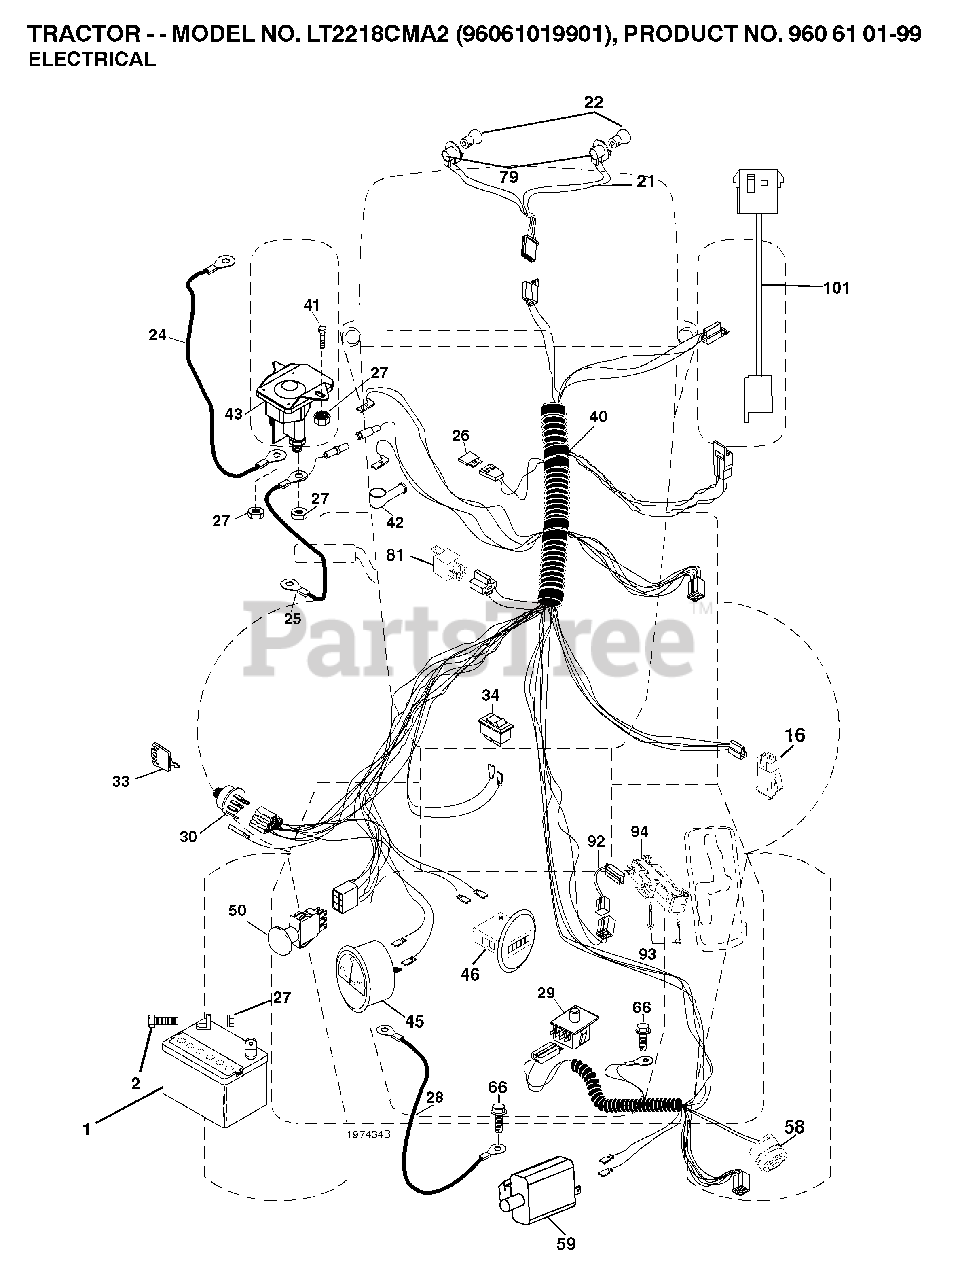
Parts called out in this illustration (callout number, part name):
1	BATTERY 12V .35 AMP
16	SWITCH INTERLOOK PUSH-IN
21	HARNESS.W/LIGHT SOCKET
22	LIGHTBULB
24	BATTERY CABLE GT
25	CABLE BATTERY
26	FUSE 20AMP
27	NUT
28	CABLE GROUND
29	SWITCH.SEAT.DP W/RAMPS
30	SWITCH.IGN.DELTA.W.LGH.ROS
33	KEY MLD GEN DELTA
34	SWITCH LT
42	TERMINAL COVER
43	SOLENOID.W/BRASS.PLUNG
46	HOURMETER SNAP-IN
50	PTO SWITCH
58	BUZZER
66	SCREW LT
79	BULB HOLDER ASM.
81	RELAY.ASSY.T
92	HARNESS.PIGTAIL.CONSLE
93	SCREW.PLASTITE
94	MODULE.REVERSE.ROS
101	PIGTAIL.MATNLK.NEW.HAR
